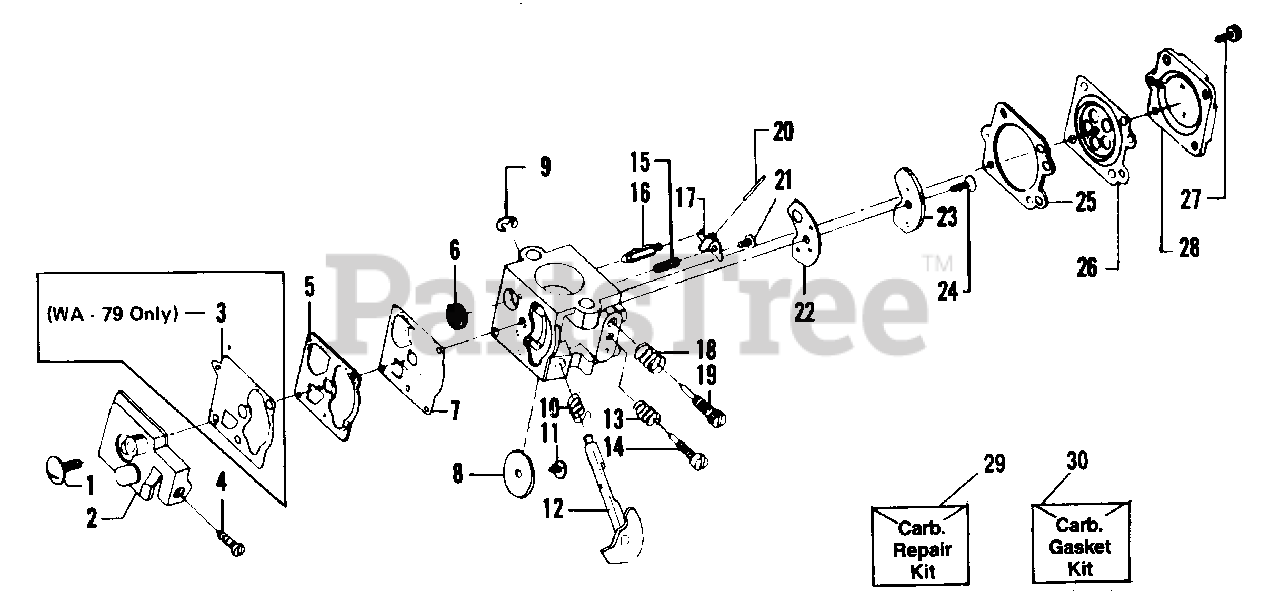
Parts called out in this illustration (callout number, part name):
1	Screw - Pump Cover
2	WA - 149 (# 35183)
3	Diaphragm - Pump (WA - 79)
4	Screw - Idle Adjustment
5	Gasket - Pump
5	WA - 149 (# 35183)
6	Screen - Inlet
7	Diaphragm - Pump
7	WA - 149 (# 35183)
8	Valve - Throttle
9	Clip - Throttle Shaft
10	Spring - Throttle Return
11	Screw - Throttle Valve
12	Shaft Assembly - Throttle
13	Spring - Idle Needle
14	Needle - Idle
15	Spring - Metering Lever
16	Valve - Inlet Needle
17	Lever - Metering
18	Spring - Hi Speed Needle
19	Needle - Hi Speed
20	Pin - Metering Lever
21	Screw - Metering Lever Pin
22	Gasket - Circuit Plate
23	Plate - Circuit
24	Screw - Circuit Plate
25	Gasket - Metering Diaphragm
26	Diaphragm Assembly - Metering
27	Screw - Assembly - Metering Cover & Throttle Shaft Clip
28	Cover - Metering Diaphragm
29	Kit - Carb. Kwik Repair
29	WA - 149 (#35183)
30	Kit - Carb. Gasket/Diaphragm
30	WA - 149 (#35183)
